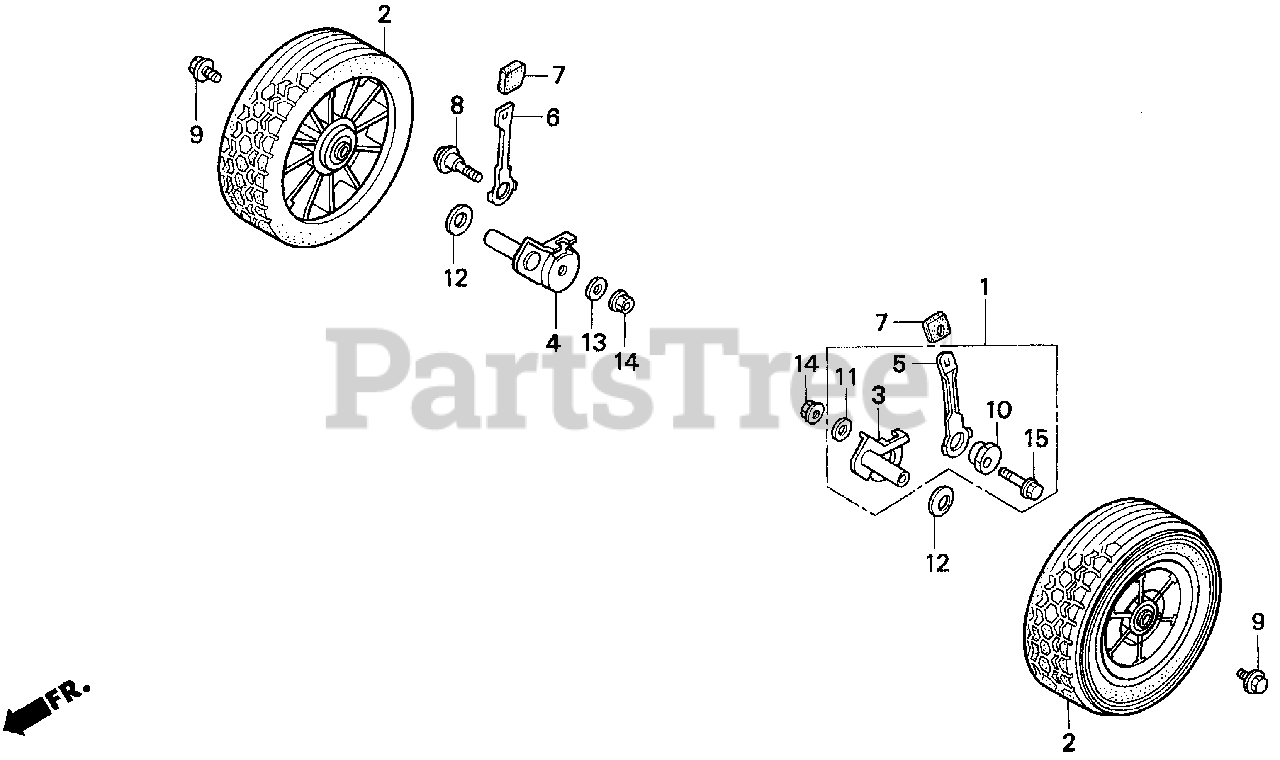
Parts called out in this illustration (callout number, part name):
1	ADJUSTING KIT, WHEEL
2	WHEEL (8") *NH31* (MCKINLEY WHITE)
3	ARM A, WHEEL ADJUSTING
4	ARM B, WHEEL ADJUSTING
5	PLATE, FR. ADJUSTING
6	PLATE, FR. ADJUSTER
7	GRIP, ADJUSTER
8	BOLT, ADJUSTING CENTER
9	BOLT, WHEEL
10	NUT, ADJUSTING
11	WASHER, HEAD (8MM)
12	WASHER, WHEEL
13	WASHER A, HANDLE HOLDER SETTING
14	NUT, FLANGE (8MM)
15	BOLT, FLANGE (8X45)
NI	TIRE (8 INCH)
NI	BEARING, RADIAL BALL
